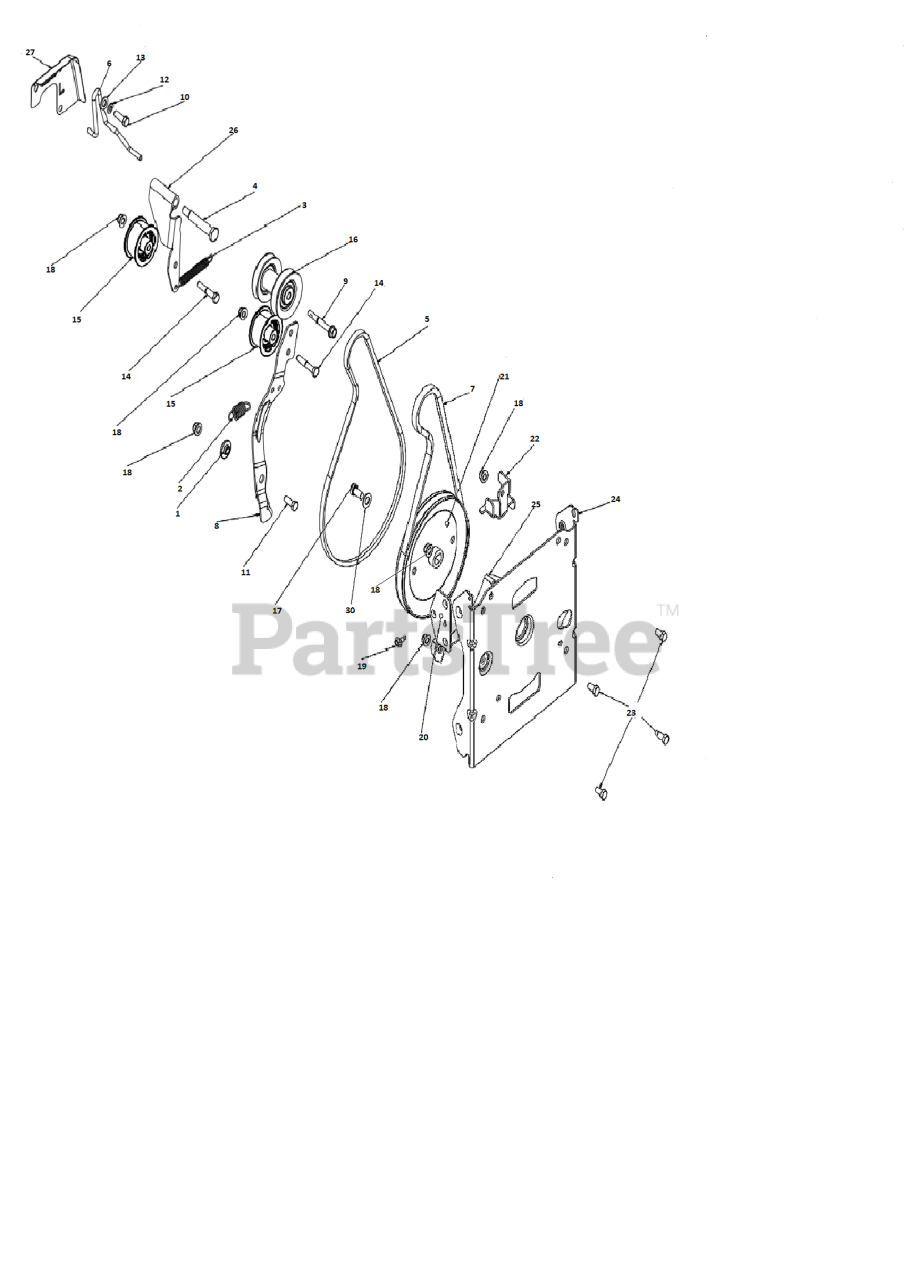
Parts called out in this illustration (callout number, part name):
1	BUSHING.BRAKE.ARM
2	SPRING RETURN, IDLER ARM, IMPE
3	SPRING RETURN IDLER ARM
4	BOLT 5/16-24X2.25 HEX HEAD SHO
6	Belt Keepers
7	LOW CRANK IMPELLER BELT
8	ARM.IDLER.AUTO-PH.676
11	BOLT HEXAGON BOLT 5/16-18 X 7/
12	WASHER SPRING LOCK WASHER WITH
13	WASHER 11/32 X 11/16 X 14 GA T
14	BOLT, HEX 5/16-18X1-3/4
15	PULLEYIDLER.2.0.W/SPACER.CZ
16	PULLEY 4L GEAR - LC
17	BOLT
17	SCREW HEXAGON HEAD FLANGE 3/8-
18	NUT HEXAGON FLANGE 5/16-18 ST
19	HEX.WASHER.HEAD 1/4-20 X .65
20	BRACKET NUT BLACK ZINC PLATE
21	PULLEY IMPELLER DD 4L
21	PULLEYS
22	GUIDE.LOWER.AUGER.BELT.479
24	BRACKET.AUG.HOUSING.INTER.BLAC
25	BRACKET.BELT.KEEPER.LOWER.BLAC
26	ARM DRIVE IDLER CLEAR ZINC PLA
30	WASHER PLAIN WASHER 3/8 X 0.08
